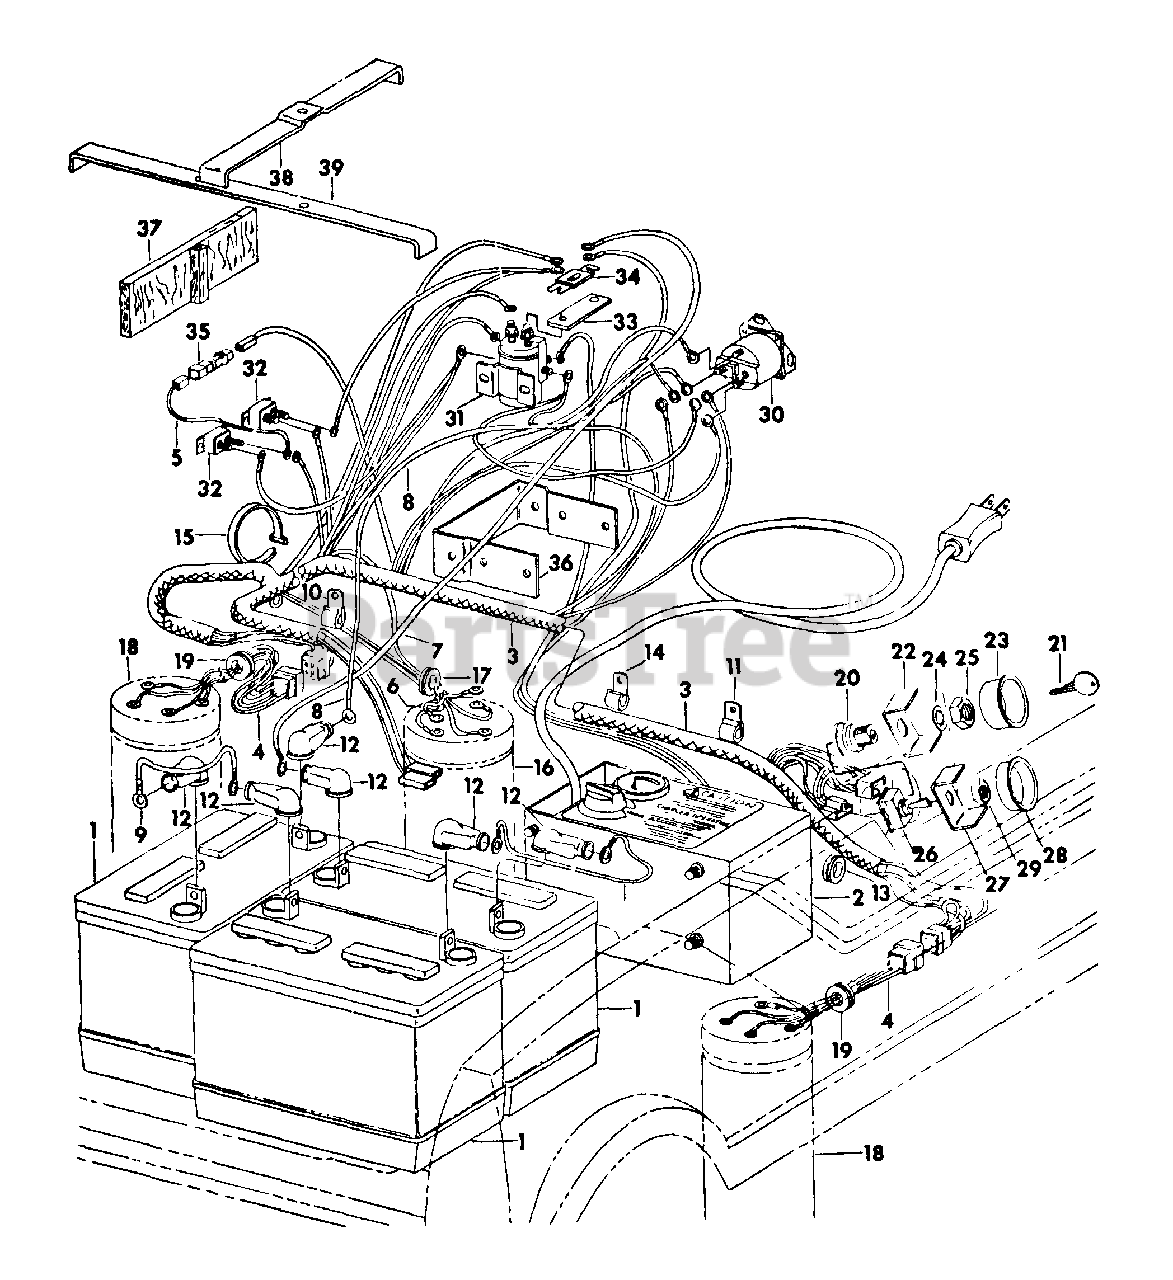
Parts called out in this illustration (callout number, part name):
1	BATTERY, 12V DEEP CYCLE
2	CHARGER, 36V DEEP CYCLE -PRESTOLITE 409464-
3	HARNESS, CABLE ELEC MOWER
4	CABLE, MOWER MOTOR
5	CABLE, DIODE TO CIRCUIT BREAKER
6	CABLE, THERMO SW. TO GROUND TRACTION MOTOR
7	CABLE, BATTERY TO MAGNETIC SWITCH
8	CABLE, BATTERY TO GROUND
9	CABLE, BATTERY TO BATTERY
10	CLIP, CABLE HARNESS
11	CLIP, CABLE HARNESS & SINGLE LEADS
12	BOOT, BATTERY TERMINALS
13	GROMMET, RUBBER
14	CLIP, CABLE HARNESS
16	MOTOR, TRACTION
17	GROMMET, RUBBER
18	MOTOR, BLADE
19	GROMMET, MOWER MOTOR
20	SWITCH, MOWER KEY START
21	KEY, MOWER KEY START
22	RETAINER, IGNITION SWITCH
23	SOCKET, IGNITION SWITCH
24	WASHER, MAGNETO IGNITION KEY MOUNTING
25	NUT, MOWER KEY START SWITCH
26	SWITCH, MOWER
27	RETAINER, MOWER SWITCH
28	SOCKET, MOWER SWITCH
29	NUT, MOWER SWITCH
30	SWITCH, MAGNETIC TRACTION
31	SOLENOID, STARTING SWITCH
32	BREAKER, CIRCUIT
33	HOLDER, FUSE
34	FUSE, 100 AMP
35	DIODE ASSEMBLY
36	BRACKET ASSY, SWITCH MOUNTING
37	SPACER ASSY, BATTERY
38	CLAMP, BATTERY
39	CLAMP, BATTERY LONG
